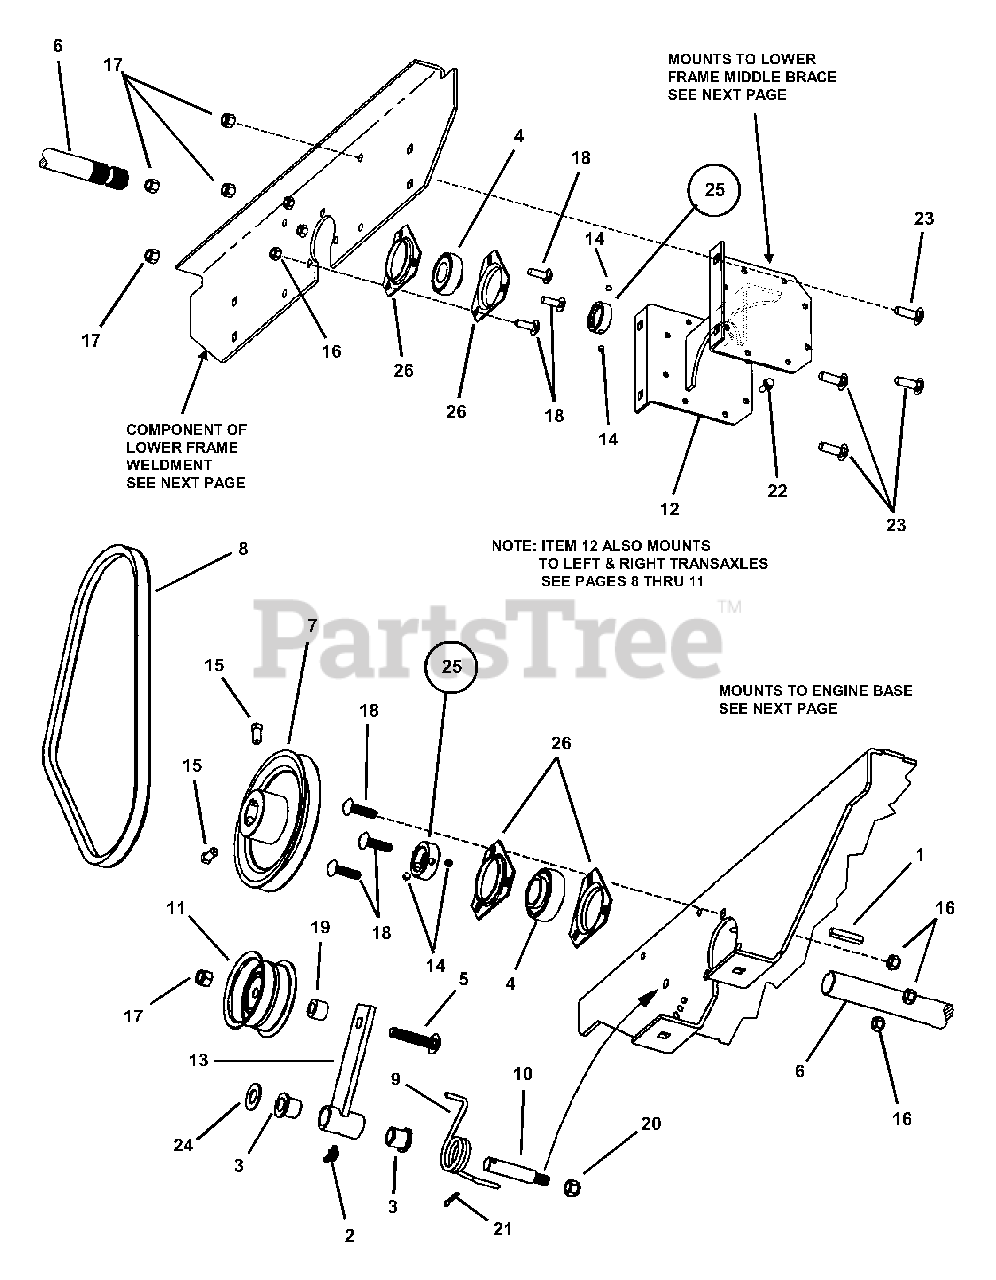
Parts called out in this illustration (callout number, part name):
1	KEY, 1/4 x 2" Square
2	FITTING, Lube
3	BUSHING
4	BEARING, 1" I.D.
5	BOLT, 3/8-16 x 2" Short Neck Carriage, Grade 2
6	DRIVE SHAFT, Deck (1" Diameter, 15 Spline)
7	PULLEY, Single V (5.75" O.D., B Section)
8	BELT, Deck Drive (AX 36.5" Effective Length)
9	SPRING, Torsion
10	STUD, Idler (3/8-24 Thread)
11	PULLEY, Idler (3.56" O.D.)
12	WELDMENT, Hydro Support
13	WELDMENT, Idler Arm
14	SET SCREW, 1/4-20 x 1/4" Socket Head, Cone Point
15	SET SCREW, 5/16-18 x 5/8" Socket Head, Knurled Point
16	NUT, 5/16-18 HEX NYLON LOCK
17	NUT, 3/8-16 HEX NYLON LOCK
18	BOLT, 5/16-18 x 1" Round Head Short Neck, Grade 5
19	SPACER, Idler
20	NUT, 3/8-24 Hex Nyloc
21	COTTER PIN, 1/8 x 3/4"
22	SCREW, 1/4-20 x 5/8" Hex Flange Lock, Grade 5
23	BOLT, 3/8-16 x 1-1/4" Short Neck Carriage, Grade 5
24	WASHER, 9/16" Flat
25	ASSEMBLY, Lock Collar, 1" (with 1/4" Set Screw, item 14)
26	FLANGE, 1" Bearing
